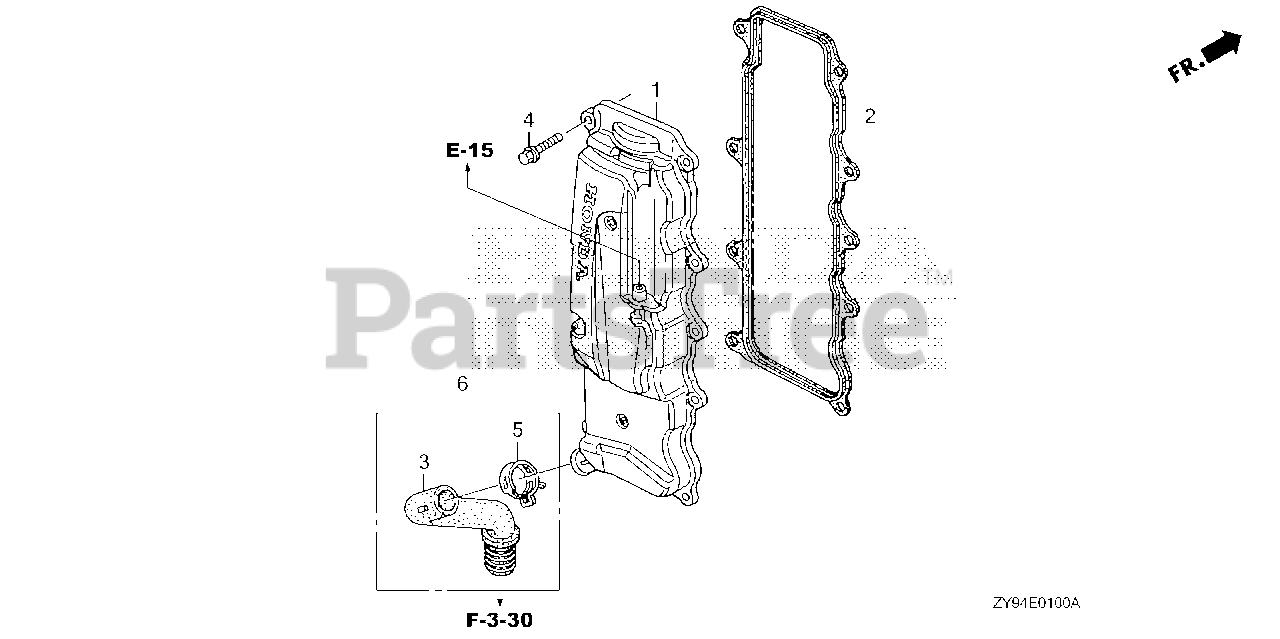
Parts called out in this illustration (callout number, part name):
1	COVER, CYLINDER HEAD
2	GASKET, HEAD COVER
3	TUBE, OIL
4	BOLT, FLANGE (6X22)
5	CLAMP, TUBE (D29)
6	TUBE SET, OIL
